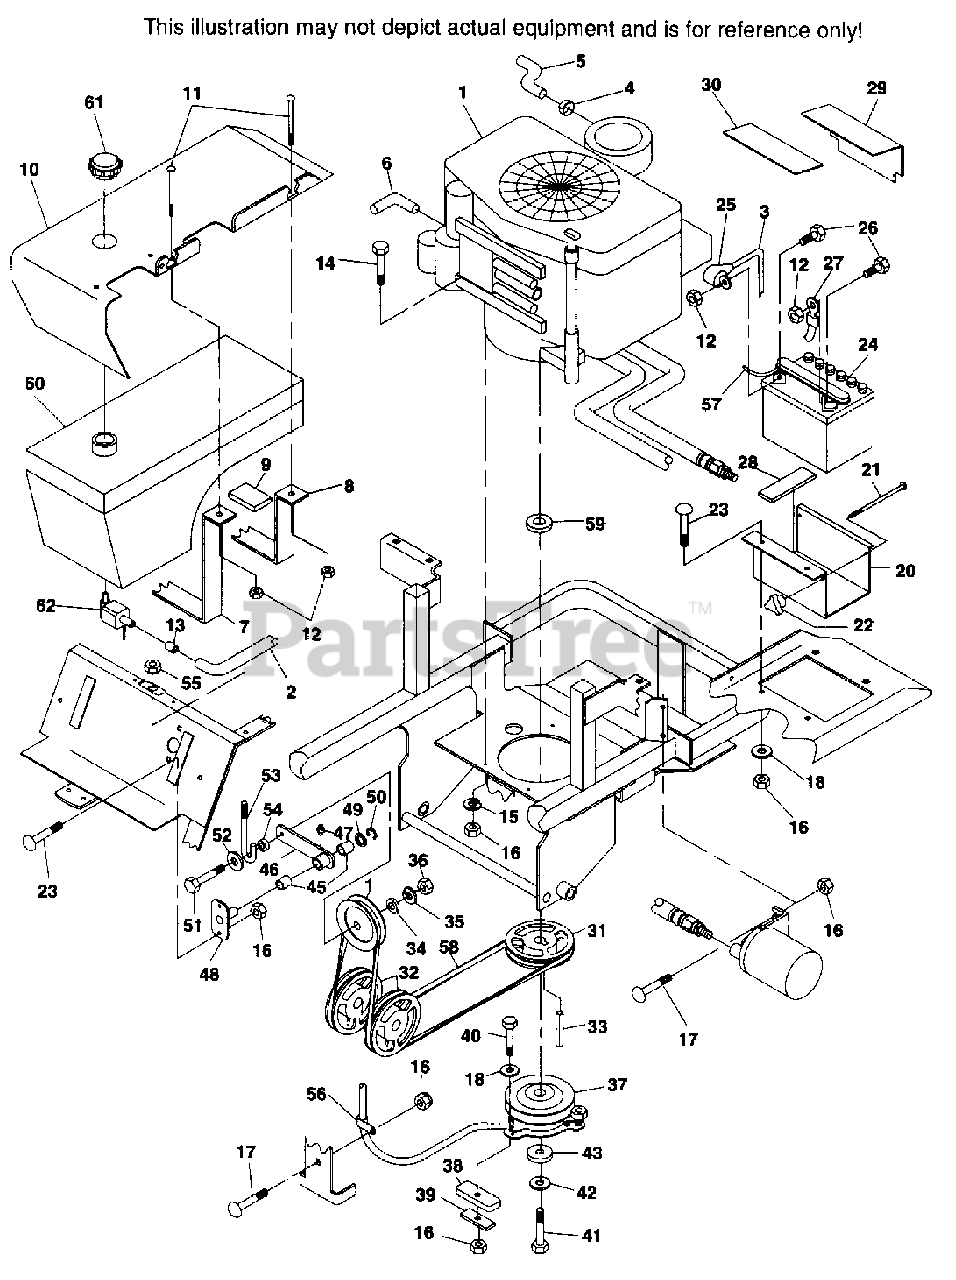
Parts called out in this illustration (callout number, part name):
1	ENGINE
2	FUEL HOSE, 36" LONG
3	BATTERY CABLE, 18" RED
6	STREET ELBOW - 3/8 NPT
7	FUEL TANK STRAP, LONG
8	FUEL TANK STRAP, SHORT
9	RUBBER PAD
10	FENDER ASSEMBLY, RH(WITH DECAL)
13	FUEL HOSE CLAMP
19	FENDER, LH
20	BATTERY BOX
22	WING NUT, 1/4-20
24	BATTERY
25	RUBBER BOOT
27	BATTERY CABLE, 27" BLACK
28	RUBBER PAD
29	BATTERY COVER
30	BATTERY COVER PAD
31	PULLEY
32	PUMP PULLEY
33	KEY, 1/4 X 1/4 X 1-1/4"
34	FLATWASHER, 3/8"
37	ELECTRIC CLUTCH
38	RUBBER PAD, CLUTCH STOP
39	BACKING PLATE
41	HEX HEAD BOLT, 7/16-20 X 3"
43	FLATWASHER, 7/16" SPECIAL
44	IDLER PULLEY
45	BUSHING
46	IDLER ARM(INCLUDES BUSHINGS AND GREASE
47	GREASE FITTING
48	IDLER PIVOT BASE
49	FLATWASHER, 3/4" SPECIAL
50	RETAINING RING, 3/4" EXTERNAL "E"
52	FLATWASHER 3/8 X 1-1/2 X .06
53	"J" BOLT
54	SPACER
57	OVERFLOW TUBE
58	BELT, PUMP DRIVE
59	SPACER, CRANKSHAFT
60	FUEL TANK(INCLUDES SHUT-OFF VALVE)
61	FUEL TANK CAP
62	FUEL SHUT-OFF VALVE
